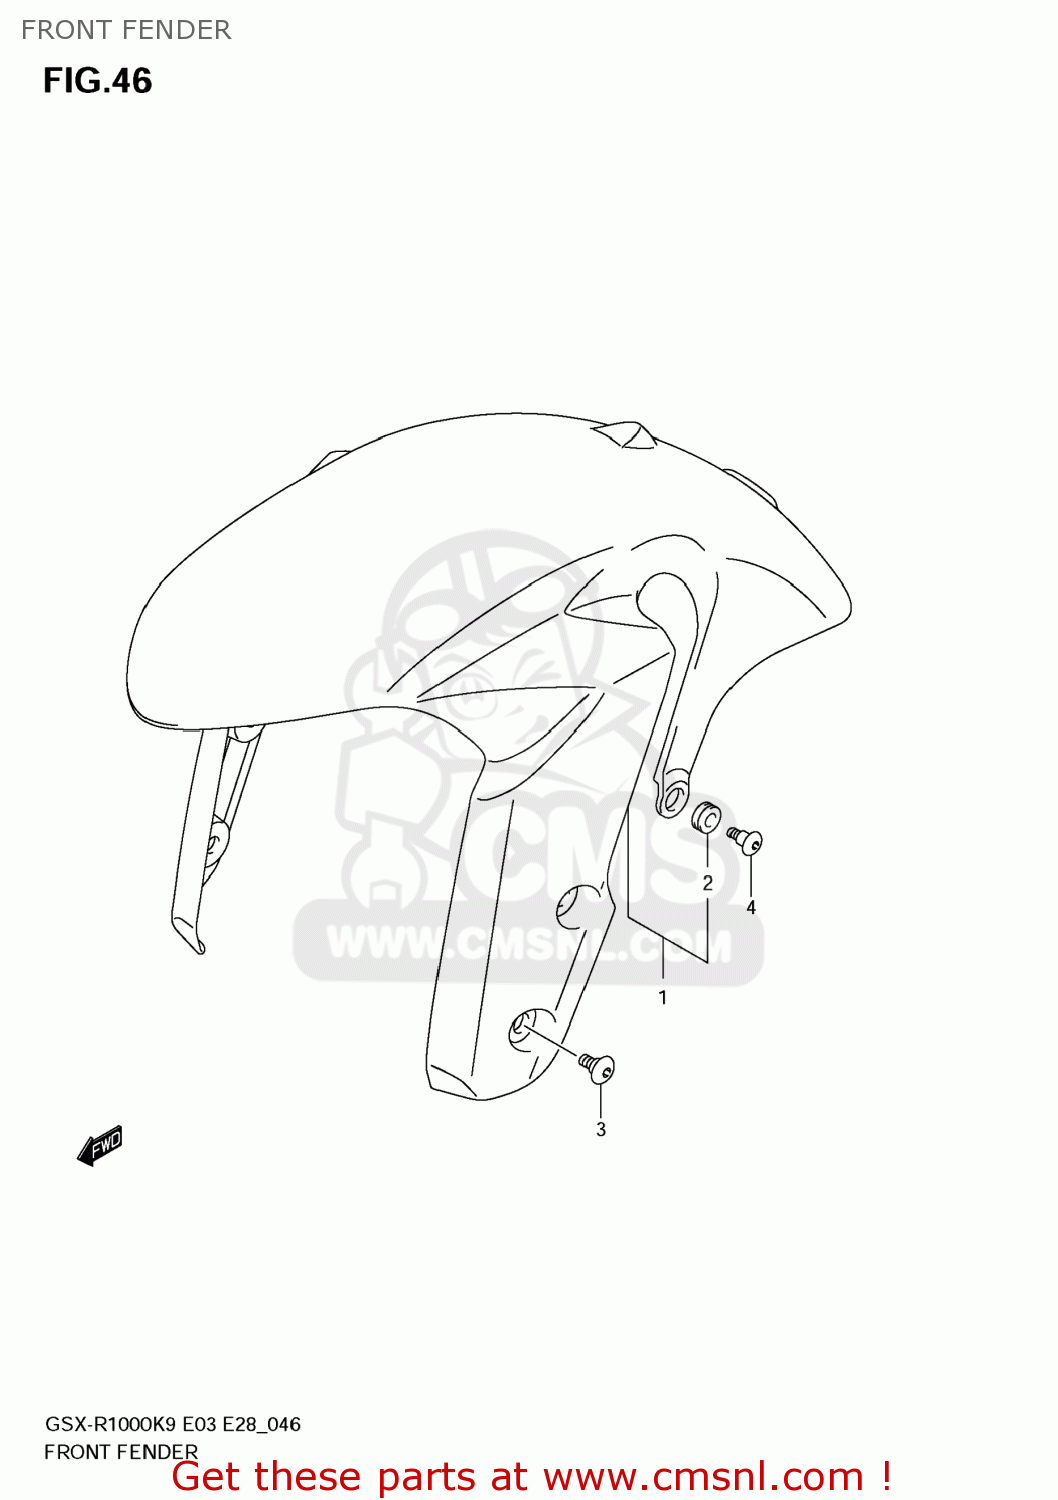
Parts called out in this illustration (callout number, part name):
1	FENDER ASSY,FR(RED)
2	CUSHION
3	SCREW(6X16)
4	SCREW(6X16)
